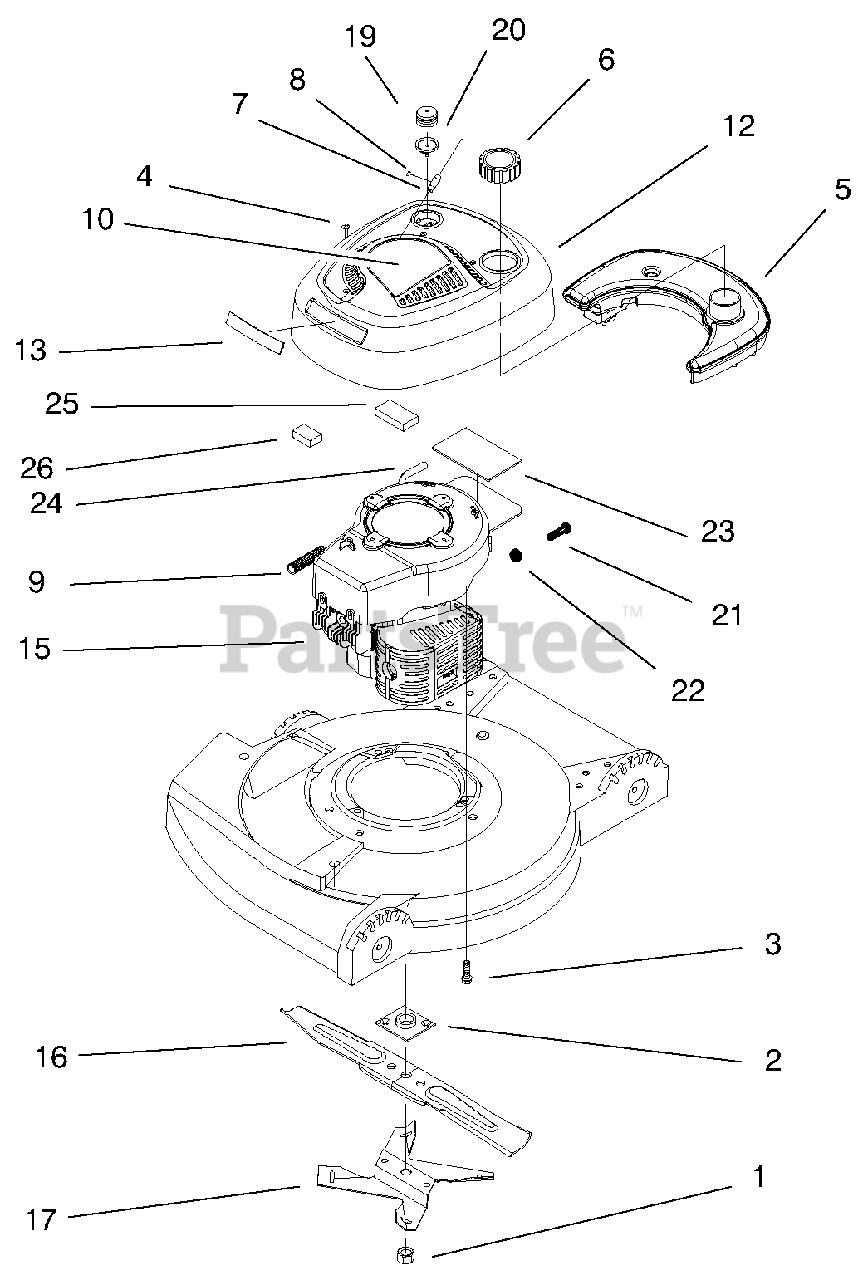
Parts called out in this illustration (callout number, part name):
1	Nut-Blade
2	ASM-Plate & Collar
3	Screw-Sems
4	Screw-Tf Acorn Hd
5	Gas Tank
6	ASM-Fuel/Oil Cap
7	Rope Stop
9	Spring-Compression
10	Decal-Recoil
12	ASM-Shroud & Recoil Covr
13	Applique-Shroud
15	Engine ASM Re Cst Hsg Hp
16	Blade-21" Whirl
17	Fan-Mulching
19	Bulb-Primer
20	Body-Primer
21	Screw-Throttle Cable
22	Nut-Throttle Cable
23	Foam Pad
24	Gas Line
25	Foam Strip
26	Foam Strip
